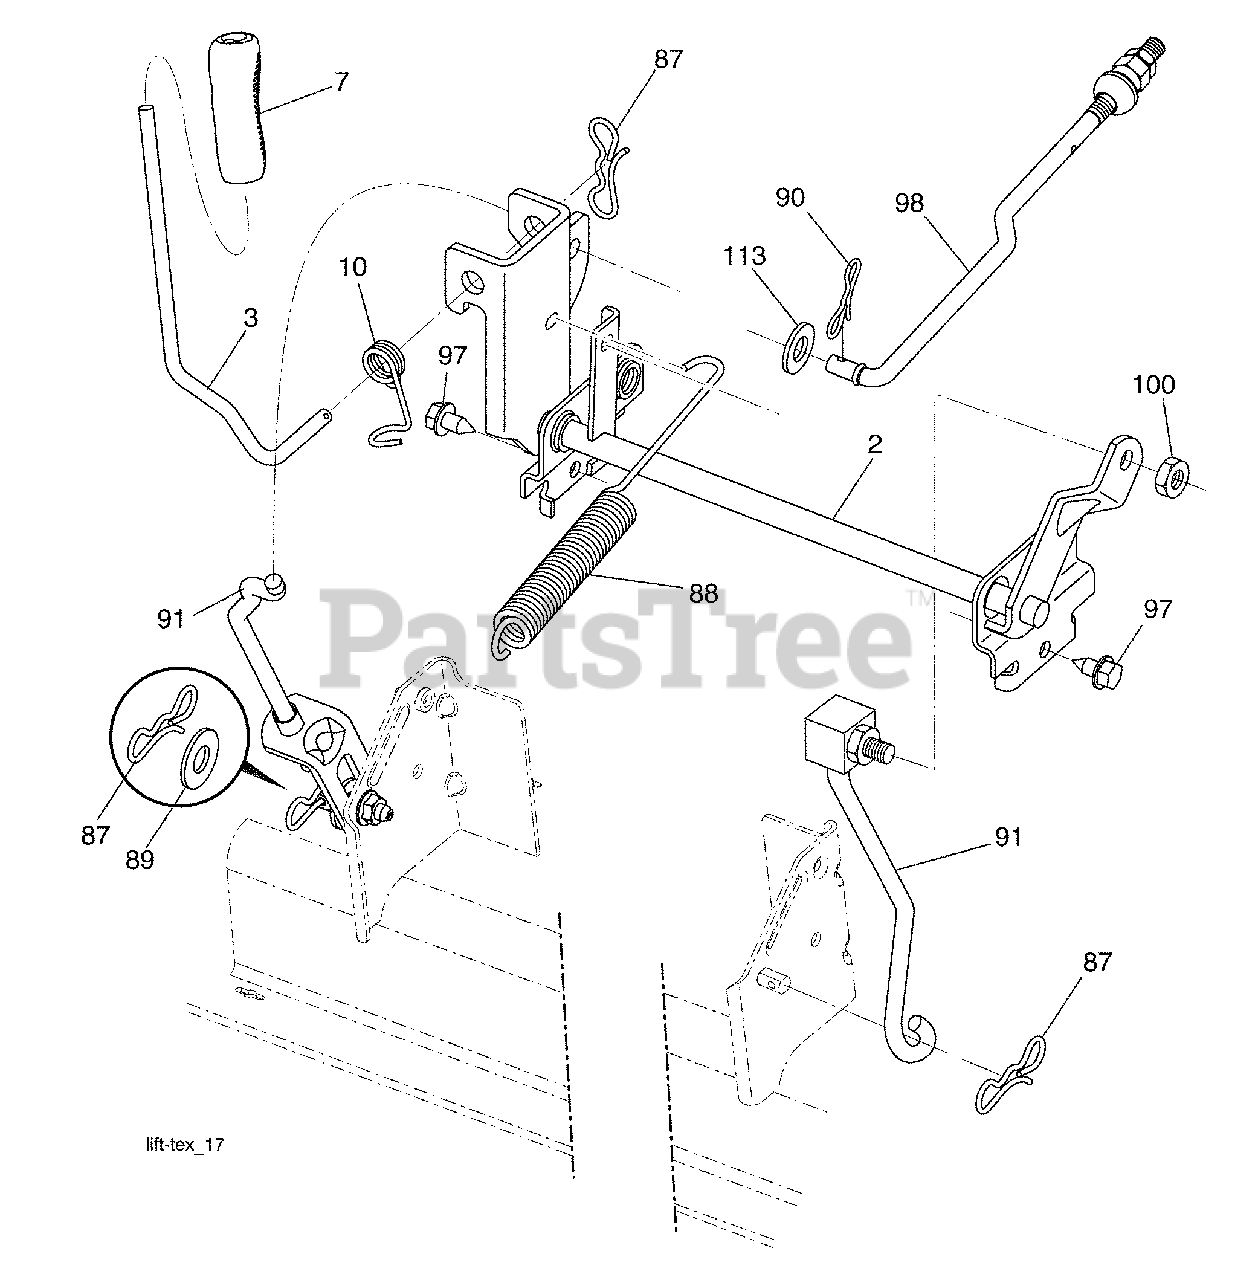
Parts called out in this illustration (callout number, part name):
2	Shaft Asm., Lift
3	Lever Asm., Lift RH
7	Grip, Lever
10	Spring Torsion
87	Pin Cotter 7/16 Bow Tie Lock
88	Spring Lift Assist
89	Washer Clear
90	Pin Cotter 5/16 Bow Tie Lock
91	Link Lift Susp Mower Rear
97	Screw 3/8-16 x .75 Smgml Tap/R.Z
98	Link Lift Susp. Front Mower
100	Nut Center Lock 3/8-16 unc
113	Washer 17/32 x 1-3/16 x 12 Ga.
